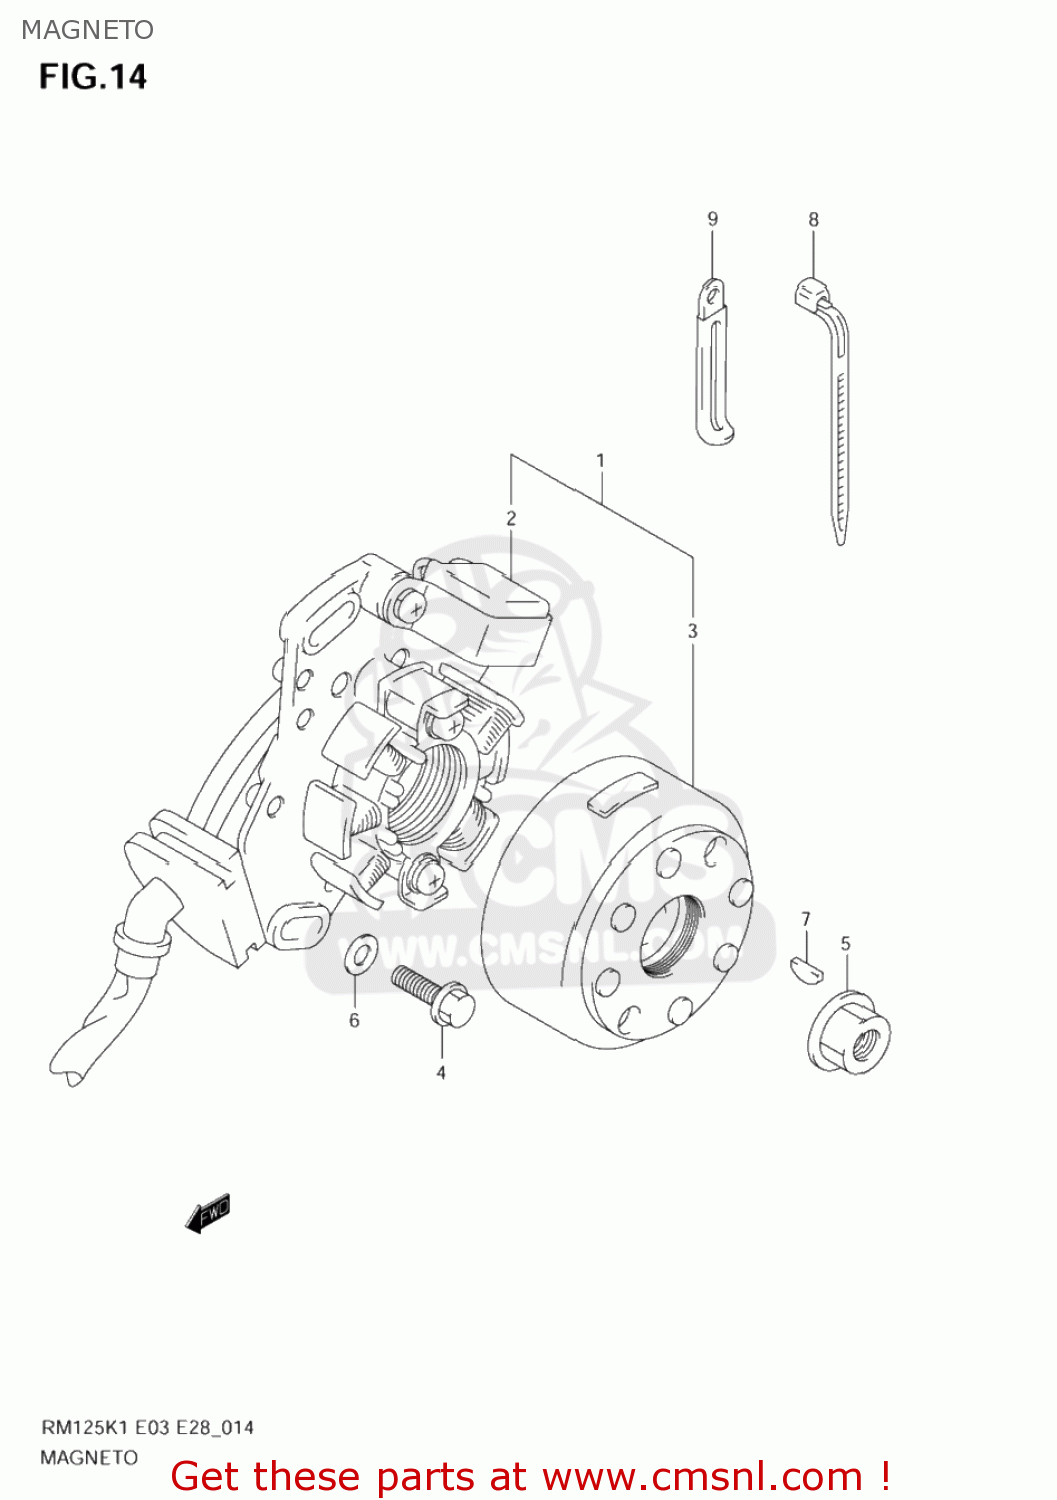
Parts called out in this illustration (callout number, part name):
1	MAGNETO ASSY
2	STARTER ASSY
3	ROTOR ASSY
4	SCREW
5	NUT
6	WASHER
7	KEY
8	CLAMP(L:165)
9	CLAMP(L:80)
